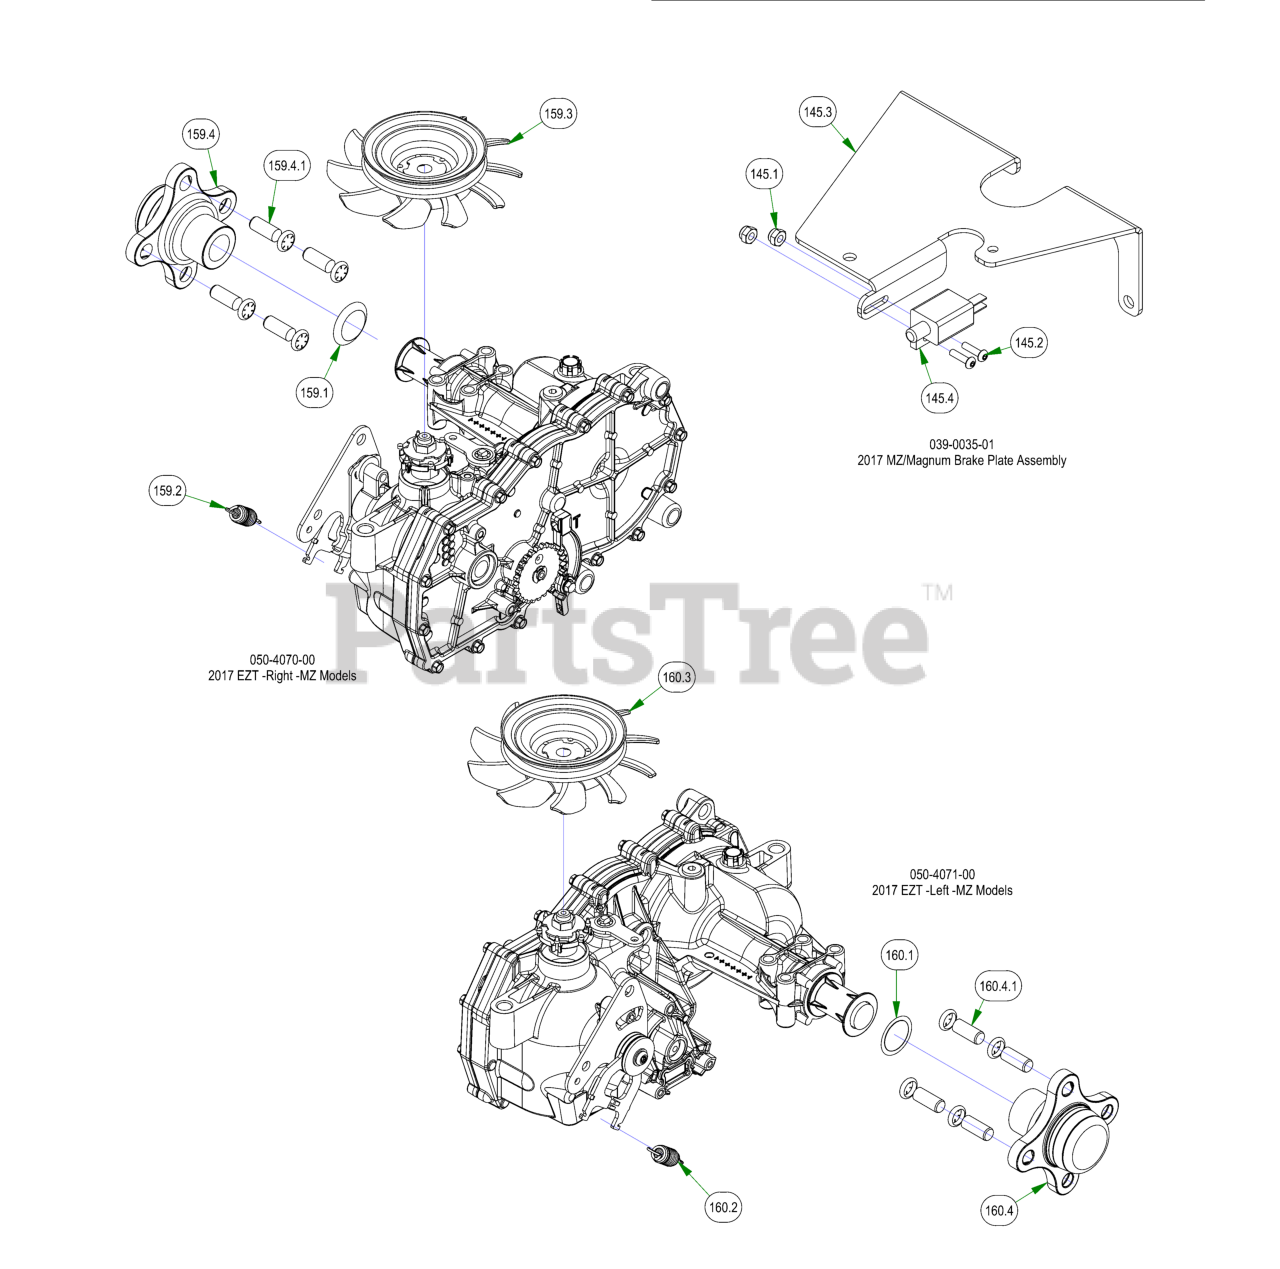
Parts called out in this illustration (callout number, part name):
145	2017 MZ/Magnum Brake Plate Assembly
145.1	#10 Nylock Nut
145.2	10-24 X 5/8 BS Button Head Bolt
145.3	2017 MZ Brake Lock Bracket
145.4	Safety Switch
159	2017 EZT -Right -MZ Models
159.1	MZ Seal & Retainer Kit
159.2	Gold Transaxle Spring
159.3	Fan/Pulley Kit for ZT / 2017 MZ
159.4	MZ 4 Bolt Hub Kit
159.4.1	Transaxle Wheel Studs/ Drum Brake Studs
160	2017 EZT -Left -MZ Models
160.1	MZ Seal & Retainer Kit
160.2	Gold Transaxle Spring
160.3	Fan/Pulley Kit for ZT / 2017 MZ
160.4	MZ 4 Bolt Hub Kit
160.4.1	Transaxle Wheel Studs/ Drum Brake Studs
